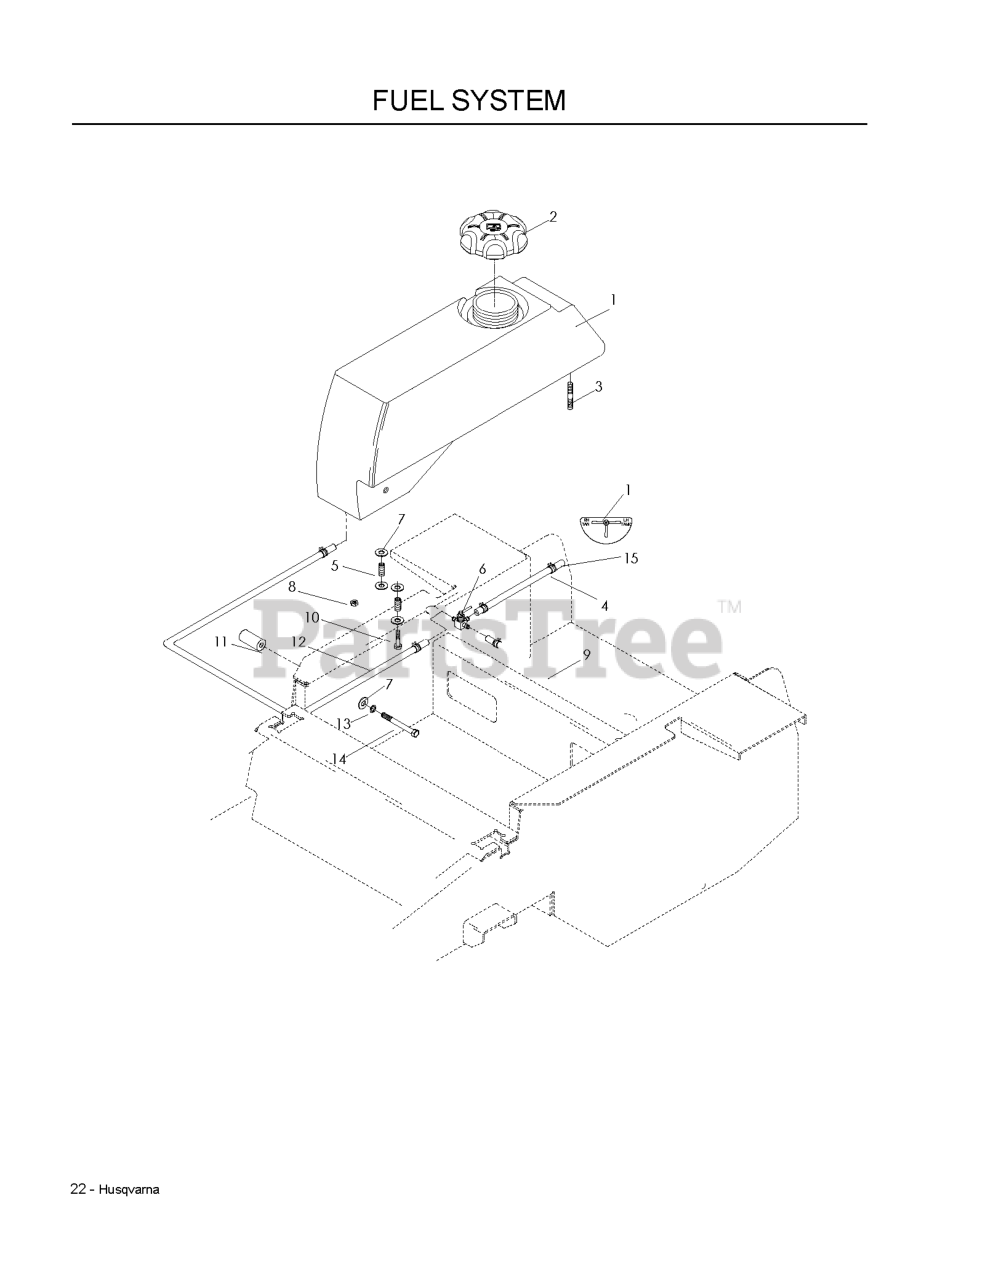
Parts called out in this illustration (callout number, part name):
1	FUEL TANK RT
2	FUEL CAP, HTC
3	STUD, 5/16C
4	HOSE CLAMP
6	FUEL VALVE
7	WASHER 5/16 FLAT
8	NUT 5/16C CENTERLOCK
10	HCS 5/16C X 1
11	TANK SPACER
13	WASHER.LOCK.HVY.HLCL.SPR.5/16
14	HCS 5/16C X 4
15	FUEL LINE 13"
16	DECAL, FUEL VALVE
